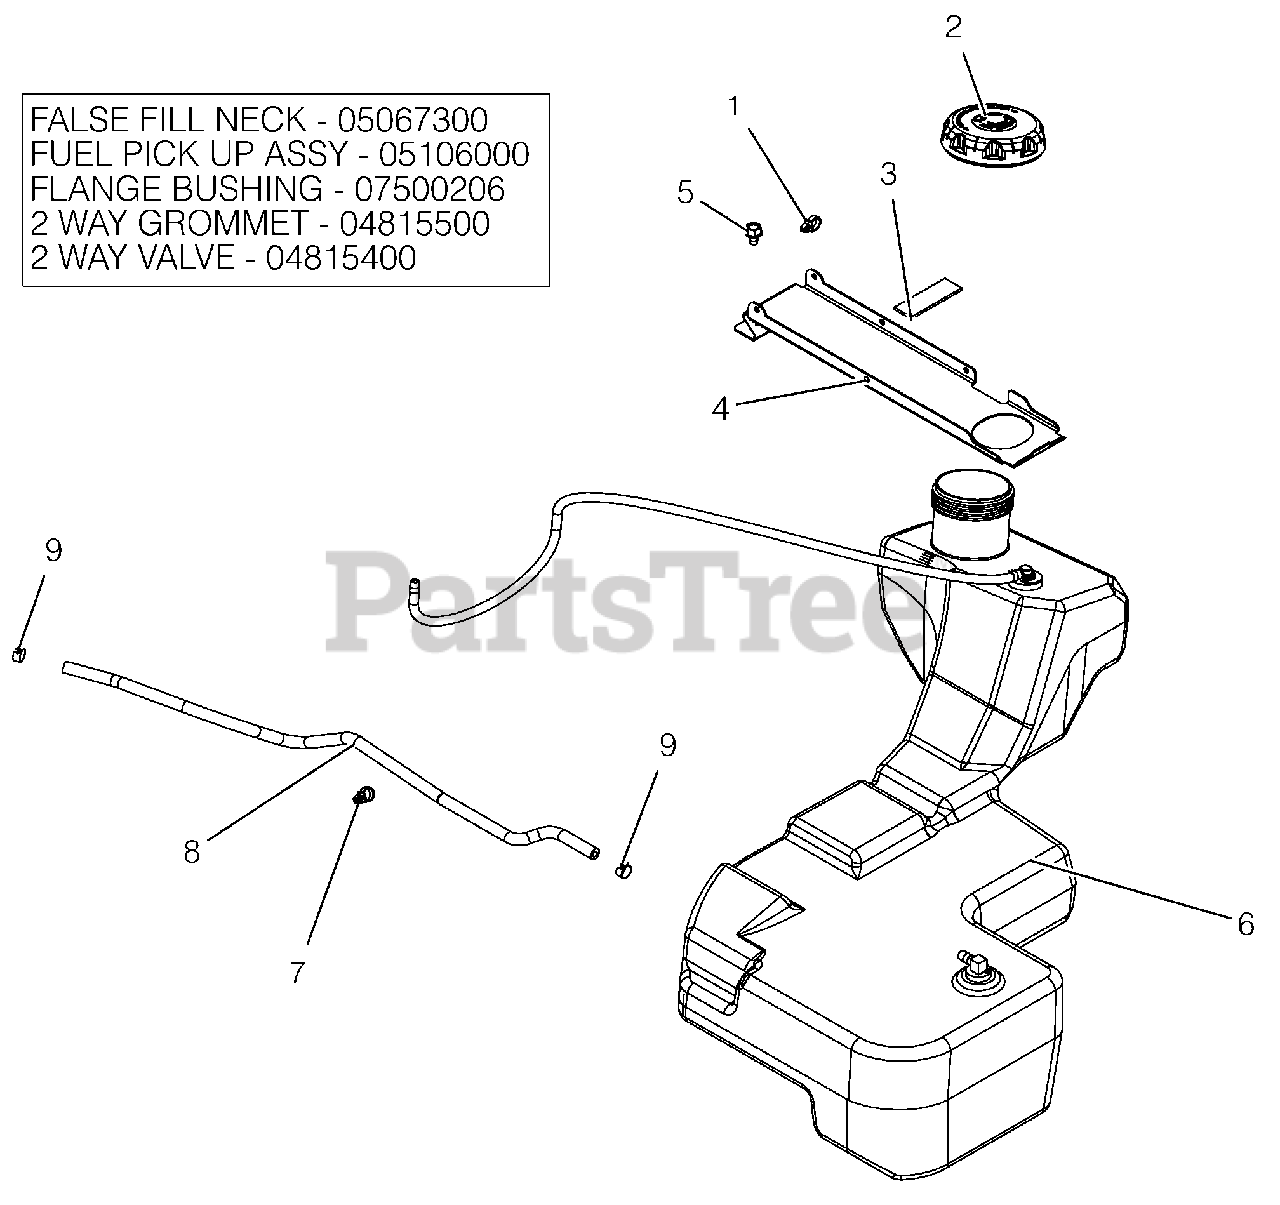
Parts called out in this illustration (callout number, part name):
1	ROUTING CLIP (1/2" ID)
2	CAP, FUEL VENTIN AUTOLOCK
3	PAD,RBR 1.0"X3.0" W/ADHESIVE
4	BRKT, FUEL TANK HOLD DOWN
5	@SCR-TAP .38-16X.50 HWH TR YWZ
6	ASM, HD FUEL TANK
6	INSERT, FUEL NECK FALSE FILL
6	ASM, HD FUEL PICK-UP
6	BSHG-FLG .375X1.062X.625 NITR
6	GROMMET, 2-WAY
6	VALVE, 2-WAY
7	ROUTING CLIP (1/2" ID)
8	HOSE, .25 LOW-PERM BULK GAS
9	CLAMP, FUEL LINE
